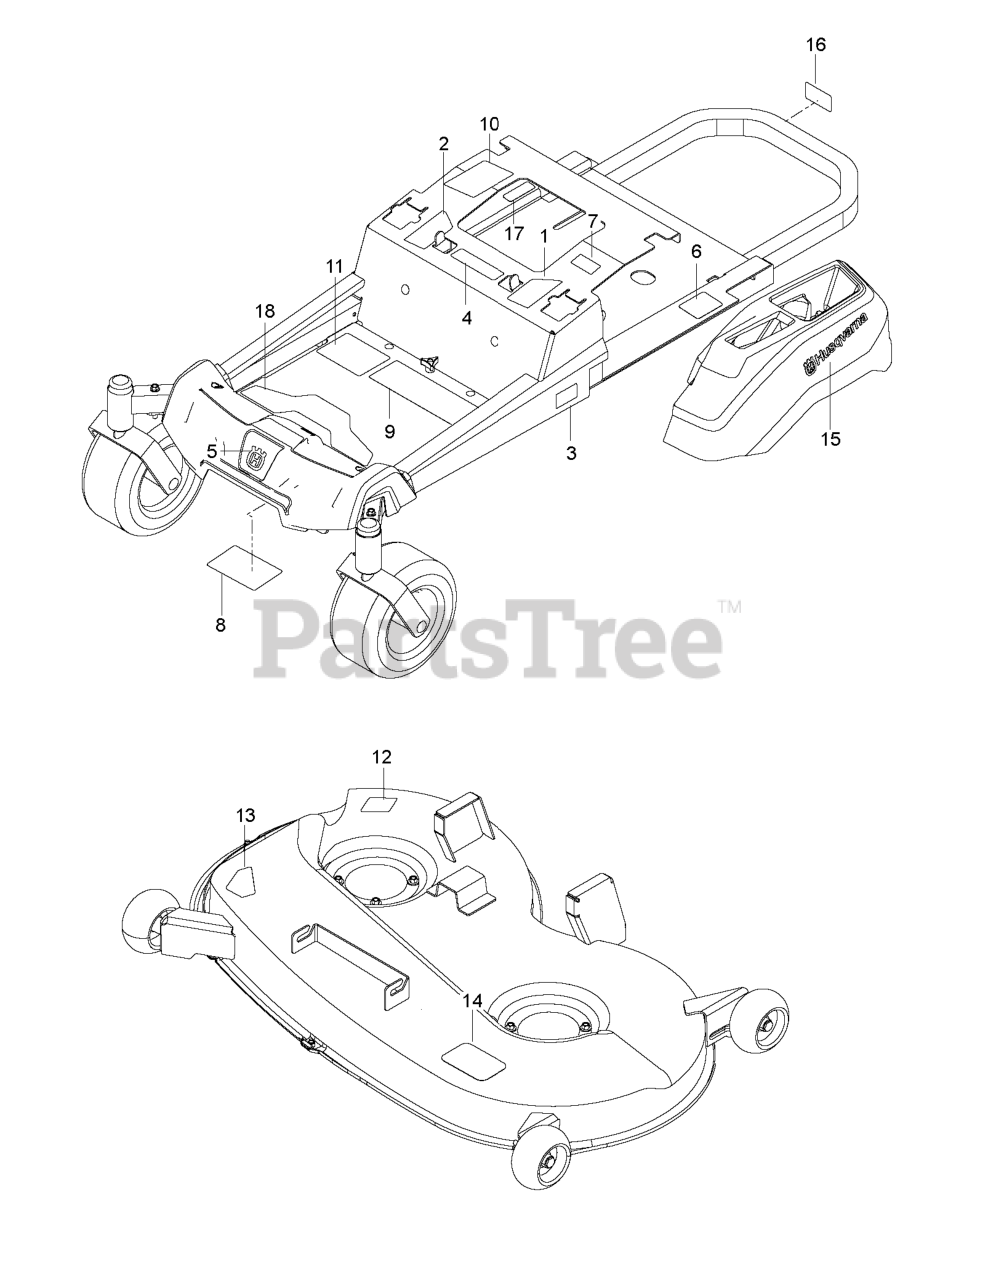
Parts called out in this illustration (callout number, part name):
1	DECAL.ZTR.RZ.THRTL/PRKBRK.V2.L
2	DECAL.ZTR.RZ.THRTL/PRKBRK.V2.R
3	DECAL.ZTR.SIDERAIL.Z246.HUSQ
4	EURO DECAL-BATTERY WARNIN6
5	DECAL.BADGE.55MM.CROWNH.HUSQ
6	DECAL, DO NOT TOW
7	DECAL, EXITING MOWER
8	DECAL, SERVICE
9	DECAL ZTR WARNING DECAL DECAL.
10	DECAL, CUSTOMER RESPNSIBILITY
11	DECAL.ZTR.STARTINS.READYSTART
12	DECAL.DECK.6MIL./DEF.SHLD.WARN
13	DECAL, DECK DEFLECTOR, WARNING
14	DECAL, BELT ROUTING
15	DECAL.HUSQVARNA.210MM
16	DECAL, PROP. 65
17	DECAL, WARNING SPARK ARRESTOR
18	PAD.RZ.FOOTREST.PLATE
